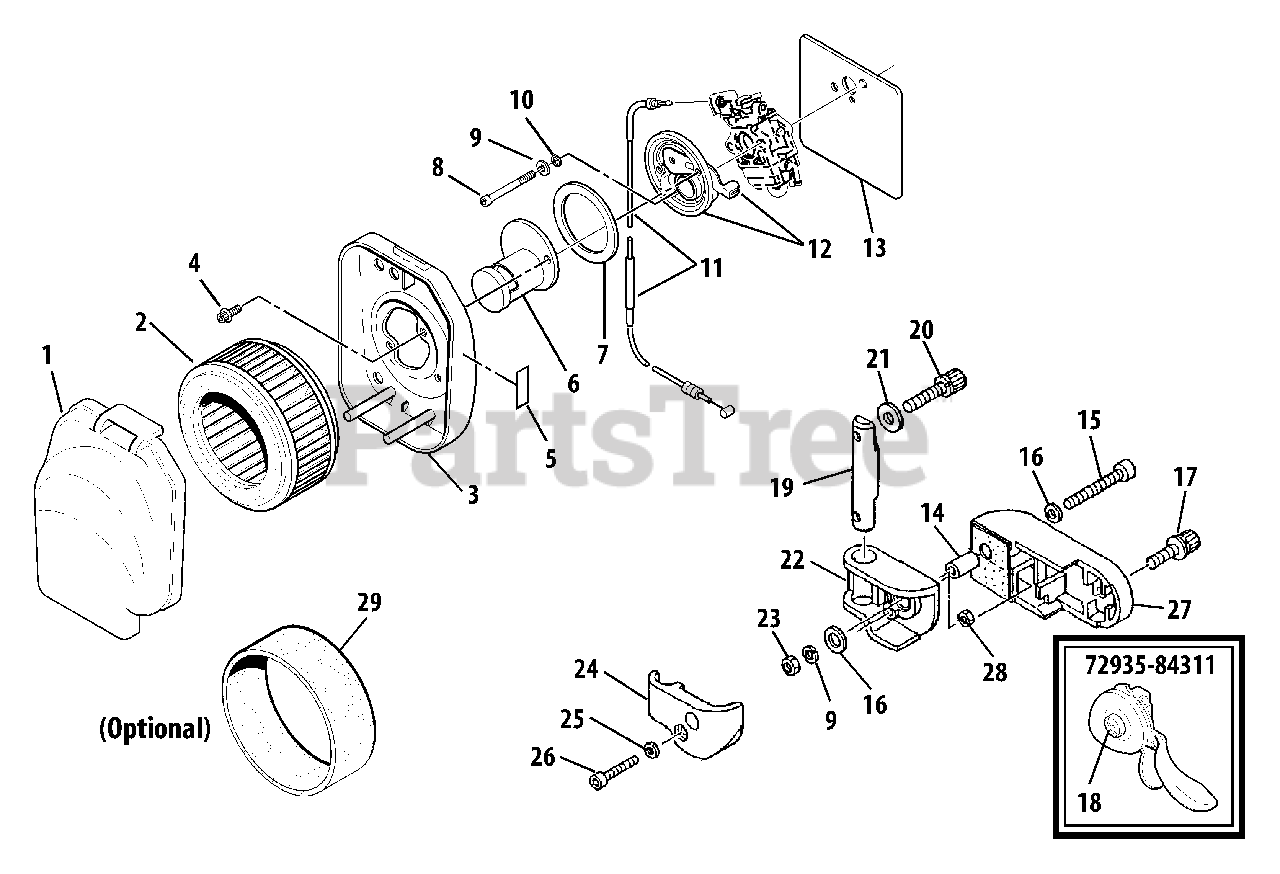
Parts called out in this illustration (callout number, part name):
1	COVER, AIR FILTER
2	FILTER, AIR
3	CASE, AIR FILTER
4	BOLT M4×14
5	LABEL, CHOKE
6	PIPE, INTAKE
7	GASKET, INTAKE
8	BOLT 5×60
9	WASHER, SPRING 5
10	WASHER, FLAT 5.5×10×0.8
11	CABLE, THROTTLE
12	CHOKE ASSY
13	GASKET, INTAKE
14	COLLAR
15	BOLT 5×25
16	WASHER
18	SCREW
20	BOLT M6×16
21	COLLAR Ø18ר6.4×L2
22	BRACKET, SWIVEL
23	NUT M5
24	COVER
25	WASHER 4 MM
26	BOLT, ADHESIVE M4×20
27	BRACKET, THROTTLE LEVER
28	NUT M4
29	PRE-FILTER, FOAM
72935-84311	TRIGGER ASSY, THROTTLE
